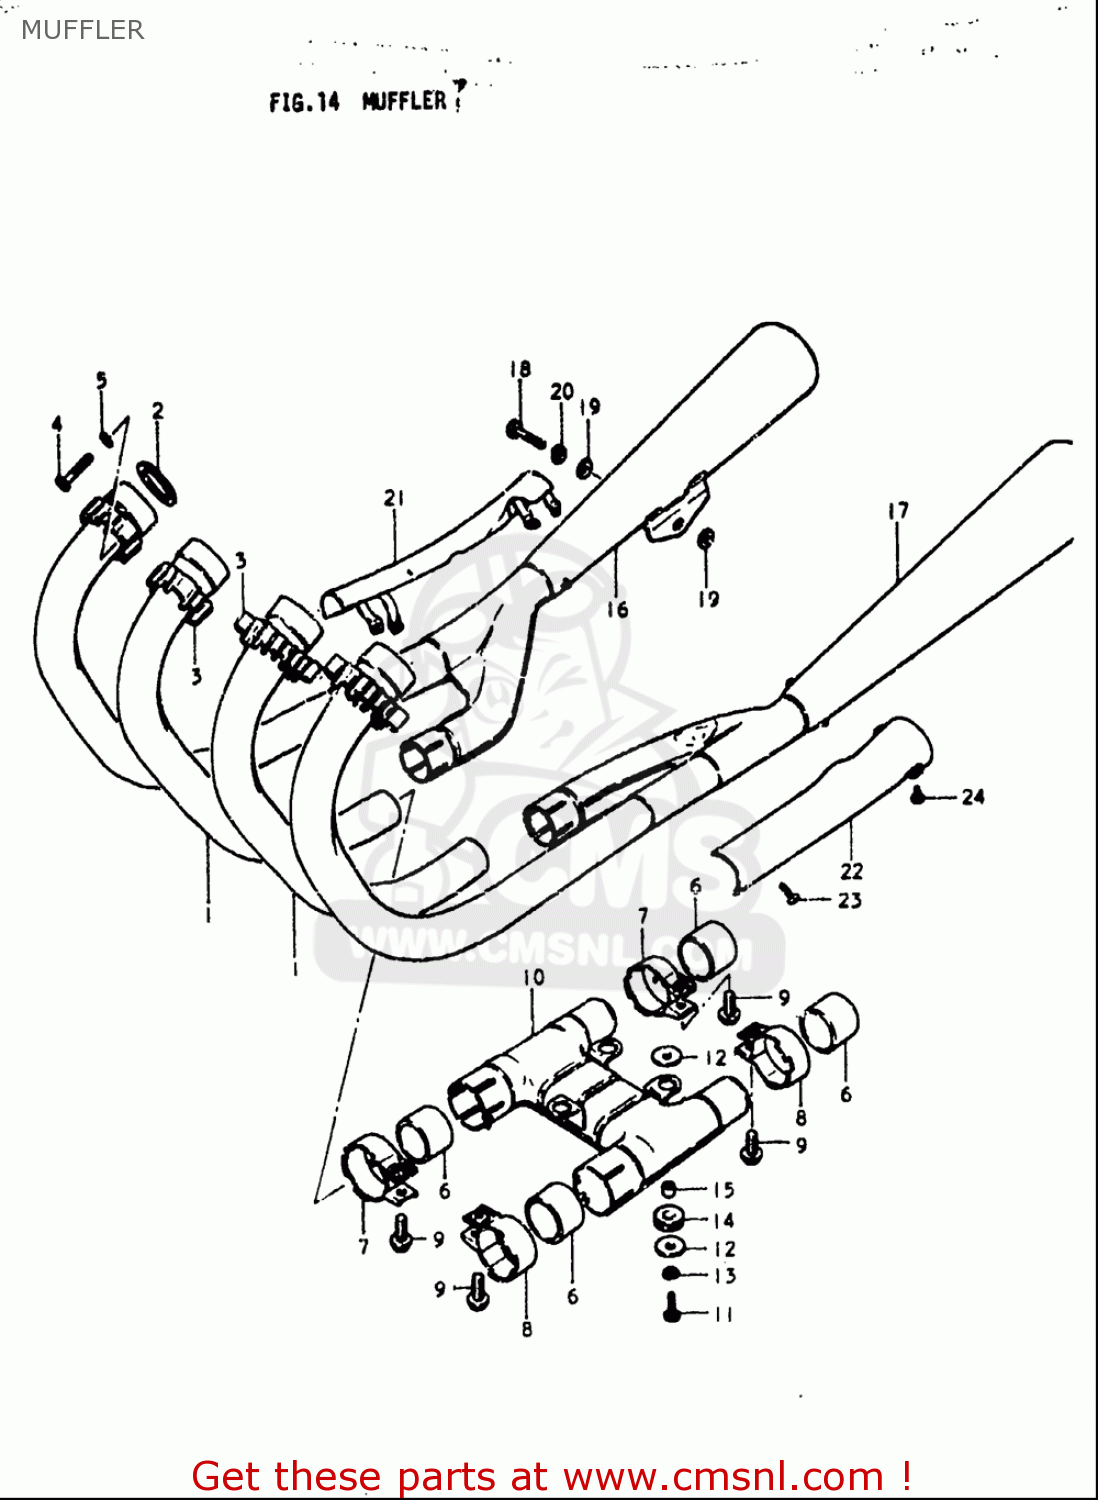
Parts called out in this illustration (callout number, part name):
1	PIPE,CENTER EXHAUST
2	GASKET,EXHAUST PIPE (NAS)
3	CLAMP,EXHAUST PIPE
4	BOLT
5	WASHER,LOCK
6	CONNECTOR,MUFFLER
7	CLAMP,MUFFLER CONNECTOR,R
8	CLAMP,MUFFLER CONNECTOR,L
9	BOLT
10	BODY,PREMUFFLER
11	BOLT
12	WASHER(6.5X24X1.6)
13	WASHER,LOCK
14	CUSHION
15	SPACER(6.5X10.5X6.5)
18	BOLT
19	WASHER
20	WASHER,LOCK
23	SCREW
24	SCREW(5X6)
